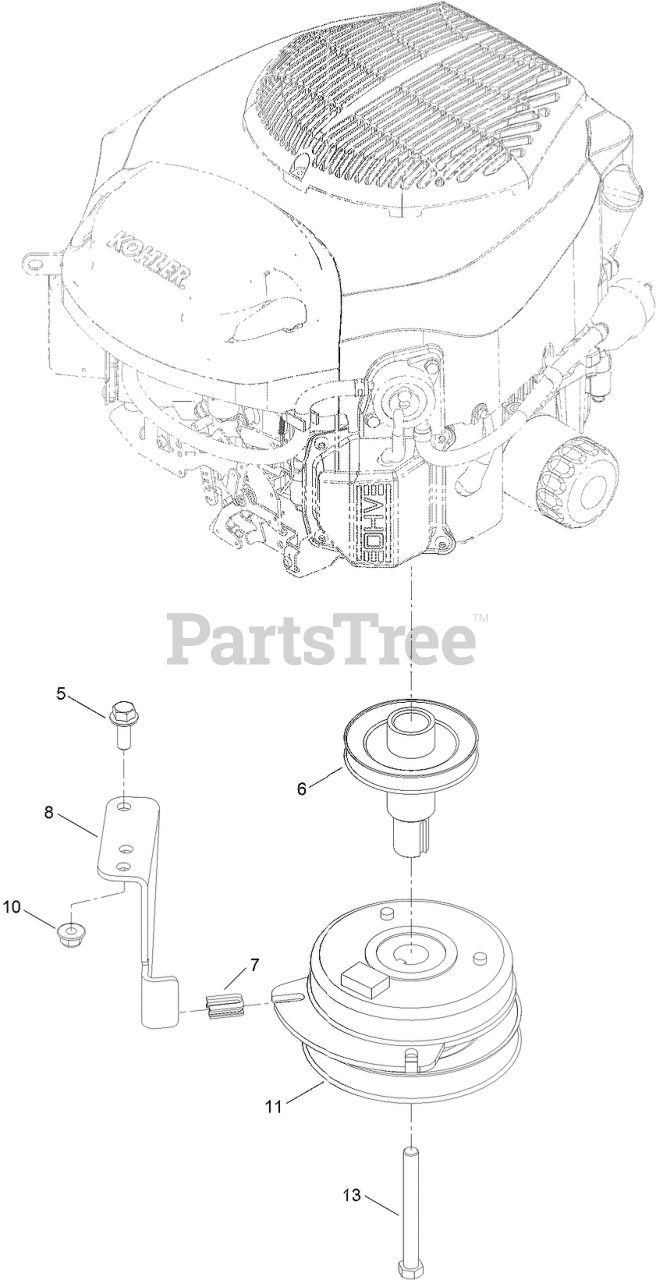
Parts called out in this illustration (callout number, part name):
5	SCREW-HHF
6	PULLEY-ENGINE
7	ISOLATOR-CLUTCH
8	STOP-CLUTCH
10	NUT-HF, NI
11	CLUTCH-PTO
13	Screw-HH
